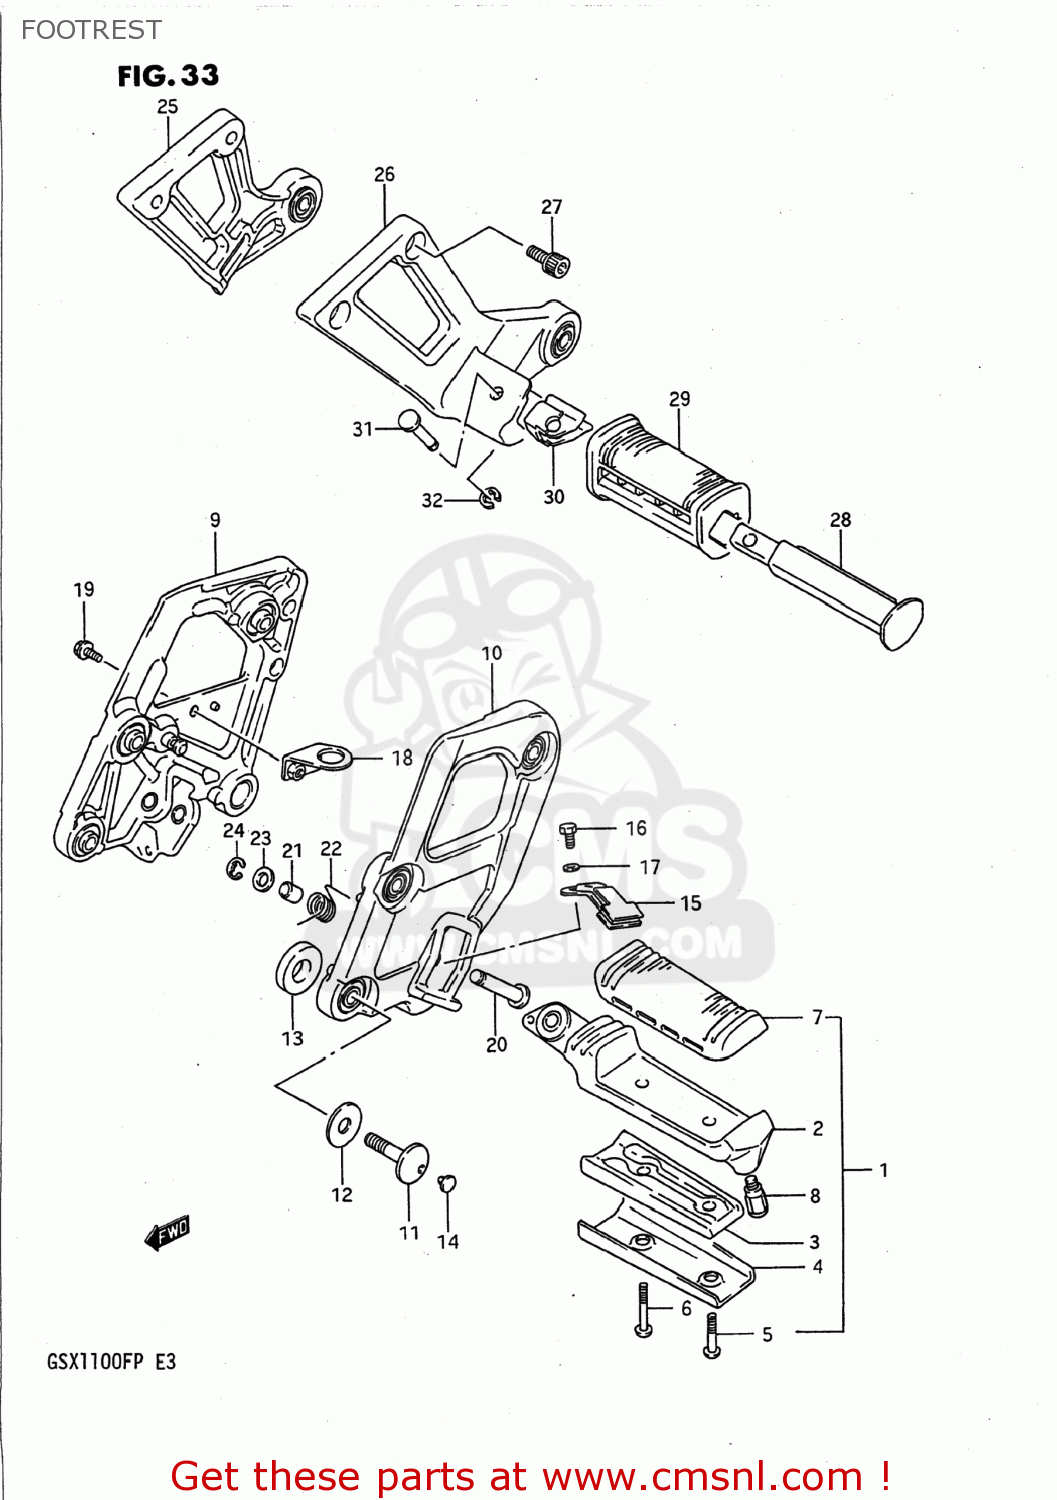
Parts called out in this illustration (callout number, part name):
1	FOOTREST ASSY,FR,R
2	BAR,FR FOOTREST,R
3	BAR,FR FOOTREST NO.2
4	COVER,FRONT FOOTREST B
5	SCREW
6	SCREW
7	RUBBER,FR FOOTREST
8	SENSOR,FOOTREST
9	BRACKET,FR FOOTREST,R
10	BRACKET,FR FOOTREST,L
11	BOLT L:30
12	WASHER
13	WASHER(12X28X5)
14	CAP(OD:10)
15	CUSHION,FR FOOTREST
16	BOLT 5X10
17	LOCK WASHER
18	BRACKET COMP,STOP LAMP SWITCH
19	SCREW(5X10)
20	PIN
21	BUSHING
22	SPRING
23	WASHER
24	E RING
25	BRACKET,PILLION FOOTREST,R
26	BRACKET,PILLION FOOTREST,L
27	BOLT
28	BAR,REAR FOOTREST
29	RUBBER,RR FOOTREST
30	CUSHION,PILLION FOOTREST
31	PIN
32	E RING
